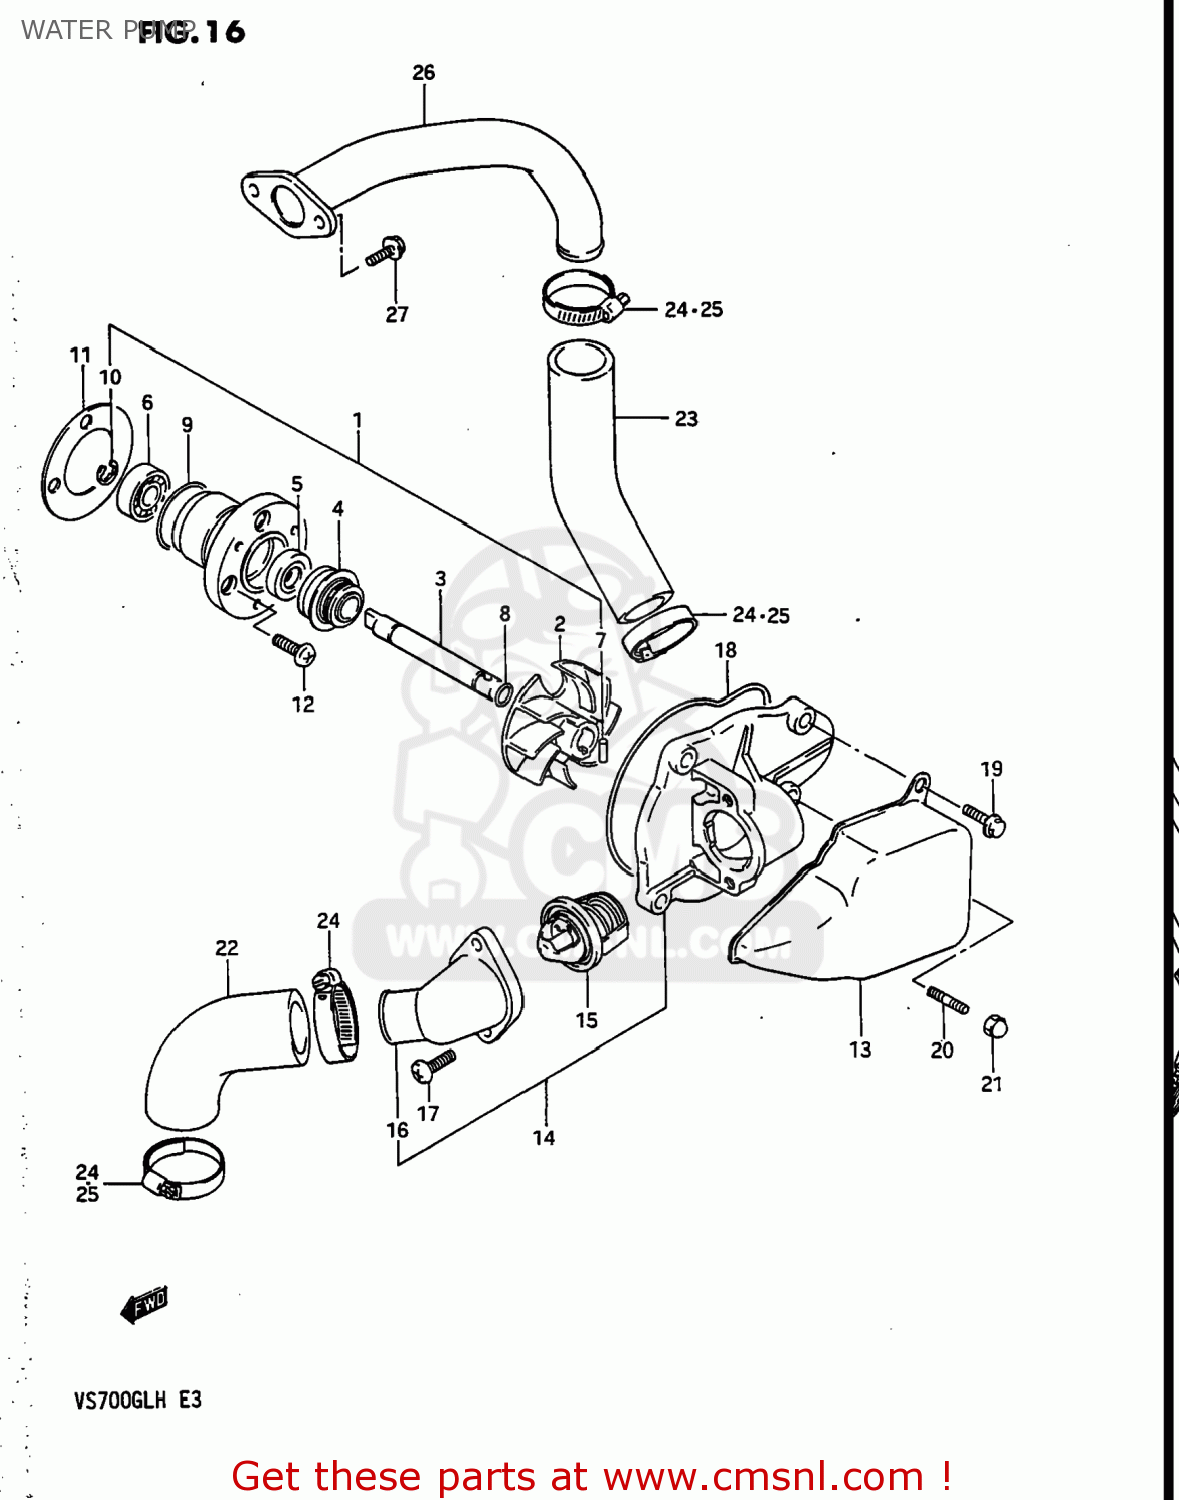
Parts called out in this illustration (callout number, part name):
1	PUMP ASSEMBLY,WATER
2	IMPELLER
3	SHAFT
4	SEAL,MECHANICAL
5	OILSEAL
6	BEARING,10X26X8
7	PIN
8	O RING
9	O RING
10	E RING
11	GASKET,WATER PUMP CASE (NAS)
12	SCREW
13	COVER,WATER PUMP
14	CASE ASSY,WATER PUMP
15	THERMOSTAT,WATER
16	CONNECTOR
17	SCREW
18	O RING,WATER PUMP CAP
19	BOLT
20	STUD
21	NUT
22	HOSE,WATER PUMP IN
23	HOSE,WATER
24	CLAMP
25	CLAMP
26	PIPE,CYLINDER INLET
27	BOLT
